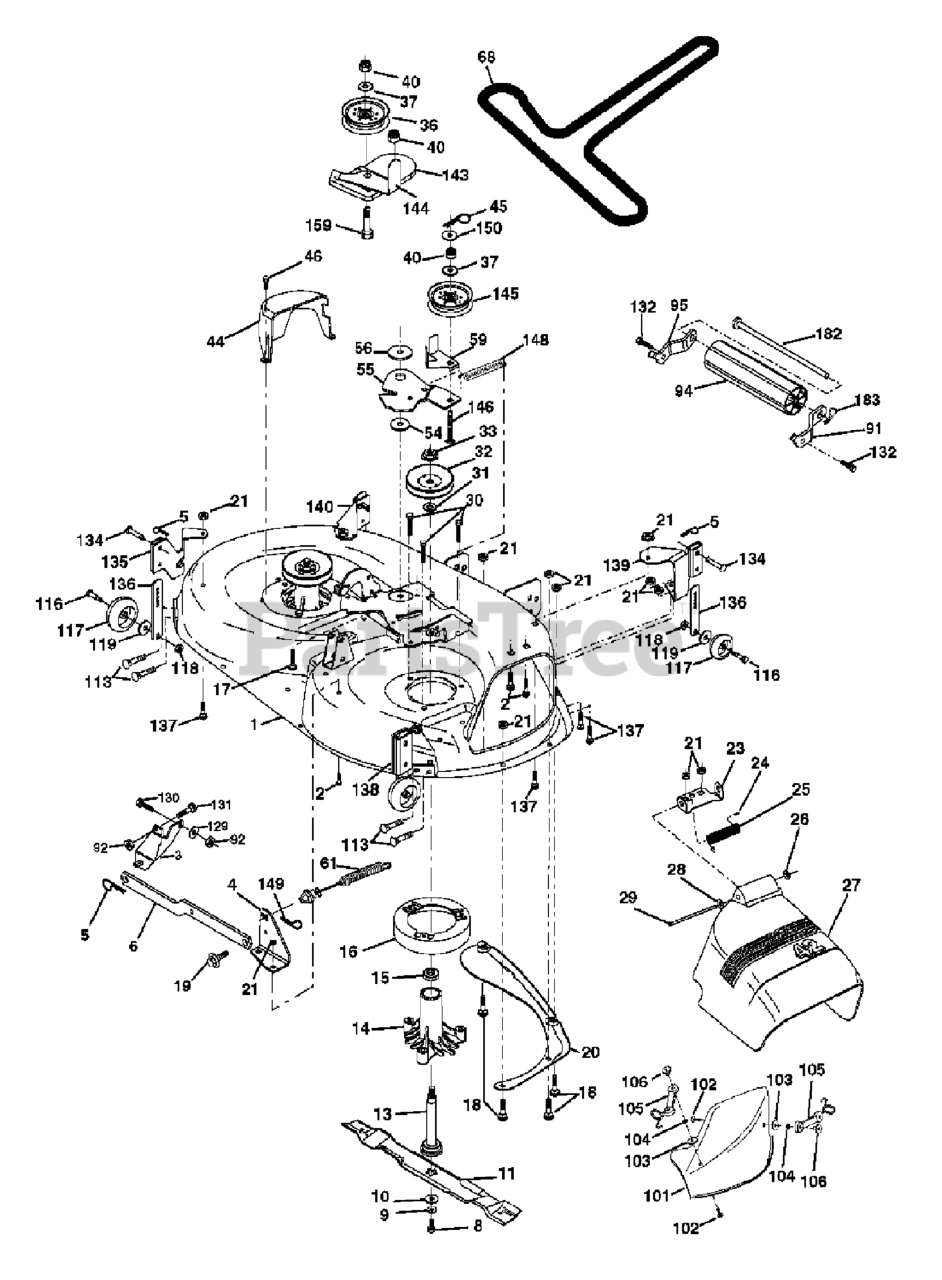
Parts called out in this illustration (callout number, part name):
1	MOWER DECK SHELL 42"
2	RP BOLT 5/16-18 X3/4 ZN/YEL GR
3	BRKT ASM SWAY BAR
4	BRACKET SWAY BAR 42" DECK
5	RETAINER-SPRNG RB
6	BAR SWAY DECK
8	BLADE BOLT
9	LOCKWASHER
10	WASHER.BLADE
11	Blade Mower 42 High Perf.
11	BLADE.42".MULCH
13	SHAFT ASM VENT
14	HOUSING.MANDREL.VENTED (MACHD)
16	STRIPPER.MANDREL.ROUND.BLACK
18	BOLT
19	BOLT SHD 5/16-18
20	BAFFLE.VORTEX
21	LOCKNUT
23	BRKT, DEFL. MOWER
24	CAP-SLEEVE LT
25	SPRING TORSION
26	NUT PUSH M
27	SHIELD DEFLECTOR
28	Washer 11/32 x 5/8 x 16 Ga.
29	ROD.HINGE
30	SCREW, WASHER HEAD
31	WASHER
32	PULLEY MANDREL
33	NUT, FLG TOPLOCK 9/16"
36	PULLEY.IDLER.FLAT
37	WASHER
44	GUARD MANDREL LH BLACK
45	RETAINER M
46	SCREW.1/4-20X5/8
55	ARM IDLER 42" MOWER LT/YT
56	SPACER RETAINER
59	GUARD TUV IDLER
61	SPRING EXT ELEC CLUTCH
68	V-BELT PRIMARY 42"
91	BRACKET ASM NOSEROLLER LH
92	NUT
94	NOSE ROLLER
95	BRACKET ASM NOSEROLLER RH
101	COVER MULCH 42"
102	SCREW
104	LOCKWASHER #10
105	LATCH ASSY
106	WELDNUT
113	SCREW 5/16"
116	BOLT M
117	WHEEL.GAUGE.STANDARD
118	LOCKNUT
119	WASHER.5/16.FLAT.STE.STD.
129	WASHER
130	BOLT
131	BOLT D
132	SCREW, 3/8-16X3/4
134	RIVET.PIN.HEAD.YELLOW.
135	BRACKET ASM, WHEEL
136	BAR.ADJUST.WHEEL.ANTI.SCALP.BL
137	BOLT.CARR.5/16-18X5/8.SHORT
138	BRACKET.ASM.WHL.GA.R.RH.42".GR
139	BRACKET ASM, WHEEL
140	BRACKET ASM, WHEEL
143	BRACKET, ARM IDLER
144	KEEPER BELT 42" CLUTCH
145	PULLEY.IDLER.FLAT.PLATED
146	BOLT CARRIAGE IDLER
148	IDLER RETURN SPRING
149	SPRING.RETAINER.YELLOW.ZINC
150	WASHER PM
159	BOLT
182	ROD ROLLER NOSE STANDARD
183	SPRING RETAINER
